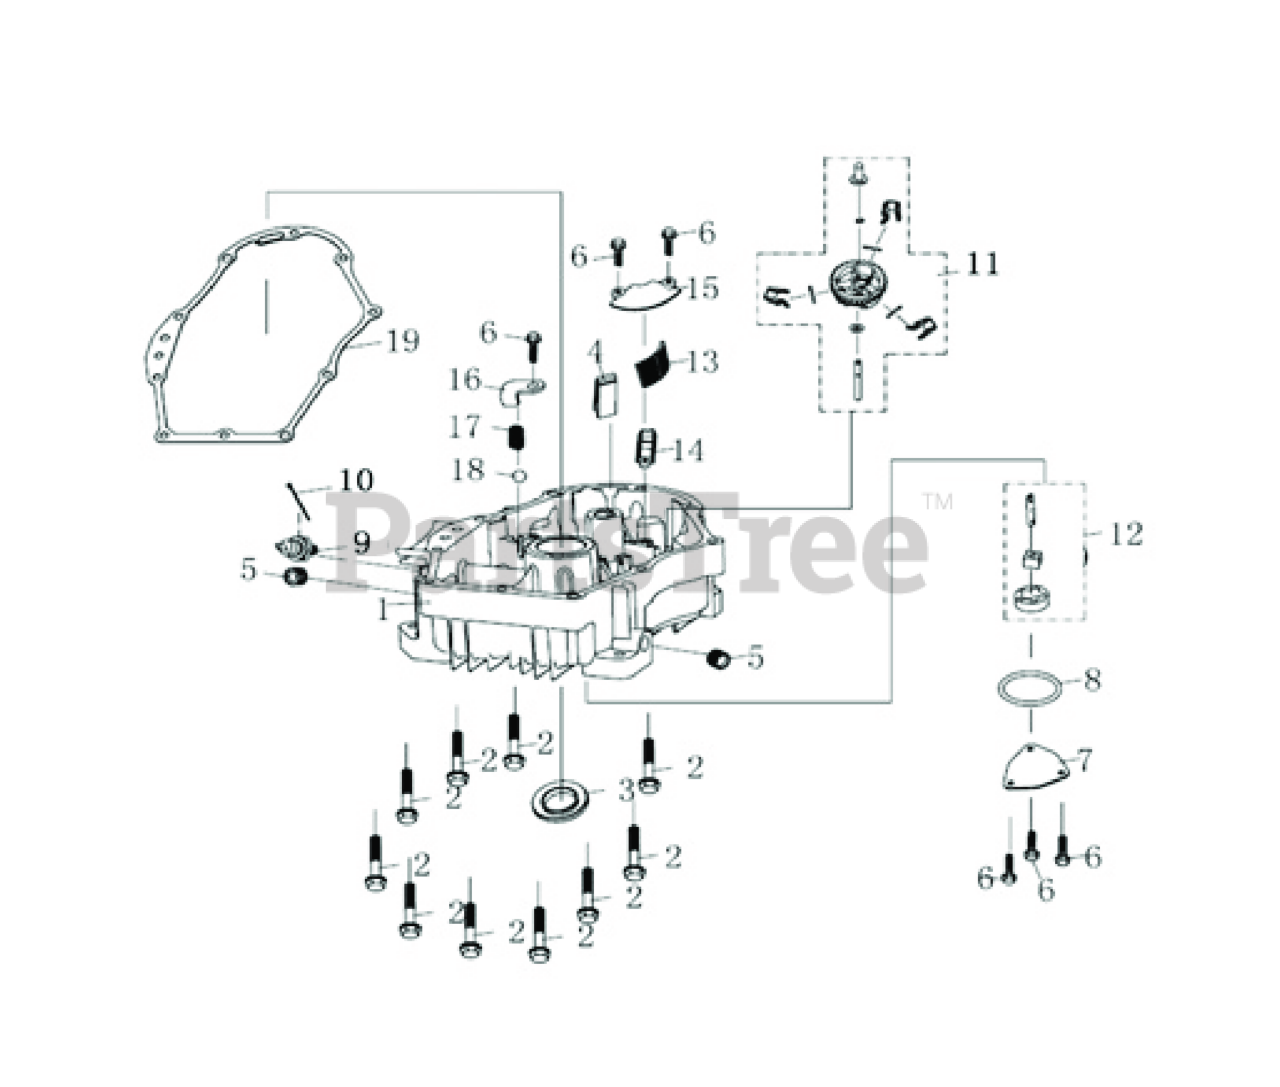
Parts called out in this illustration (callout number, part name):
1	Bushing, oil lube - 3/4 x .50 Flanged
2	Bolt, Flange
3	Seal, Oil
4	Block, Oil Return
5	Screw, Sealing Plug
6	Bolt, Flange
7	Cover, Oil Pump
9	Oil Level Sensor
10	Cable Tie
11	Governor Assembly
12	Oil Pump
13	Strainer, Engine Oil
14	BUSHING, OILITE, 2.505 ID
15	Cover, Oil Strainer
16	Plate, Oil Baffle
17	Spring, Compression
18	Check Ball
19	BUSHING, OILLUBE - 1/2 ID X .56
